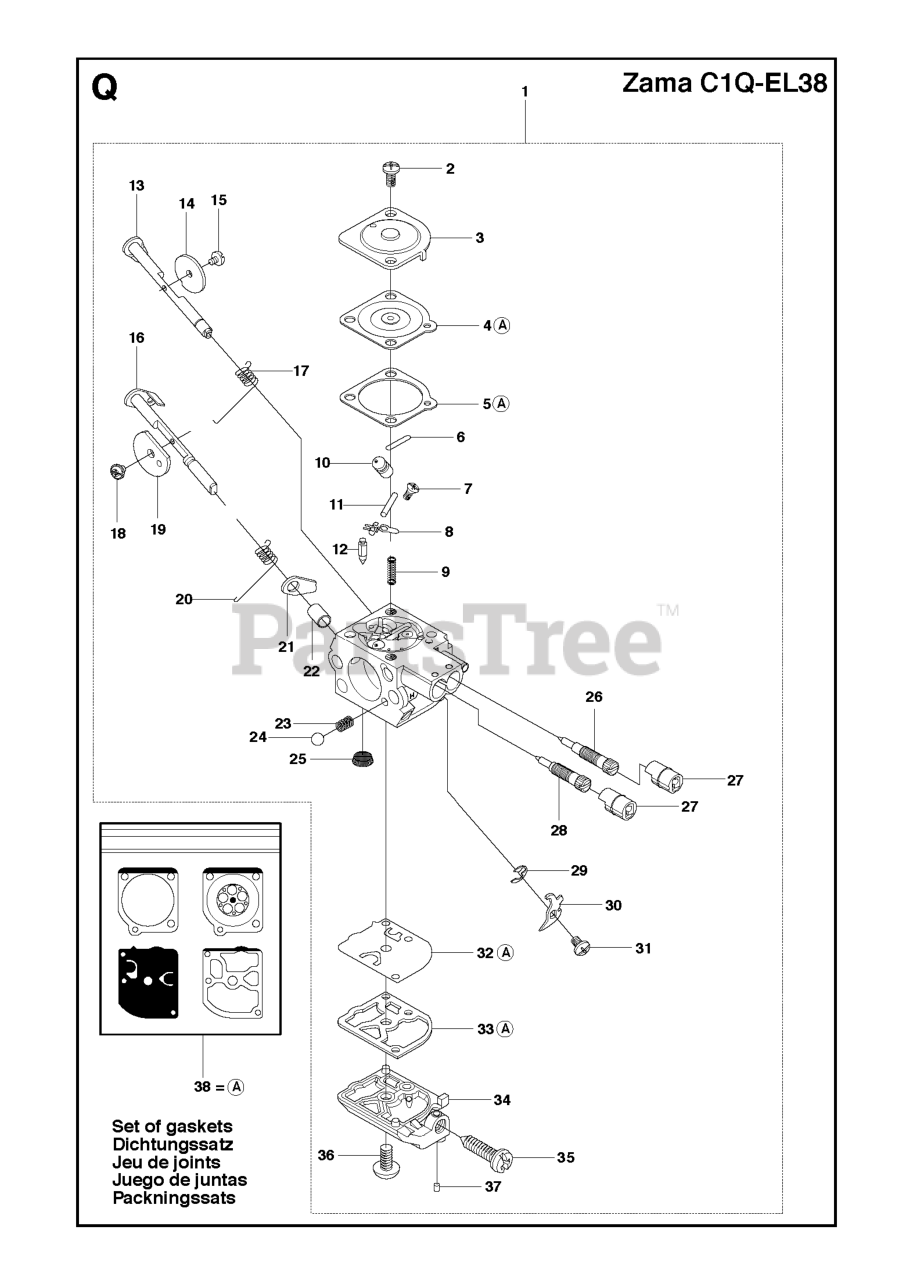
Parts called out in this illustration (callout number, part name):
1	CARBURETTOR C1Q-EL38
9	SPRING
11	PIN RETAINING SCREW
12	INLET NEEDLE
13	SHAFT ASSY
16	SHAFT ASSY
17	RETURN SPRING
25	FUEL INLET SCREEN
26	IDLE SCREW
27	LIMITER CAP KIT
28	SCREW
32	PUMP DIAPHRAGM
38	GASKET KIT (ZAMA GND39)
